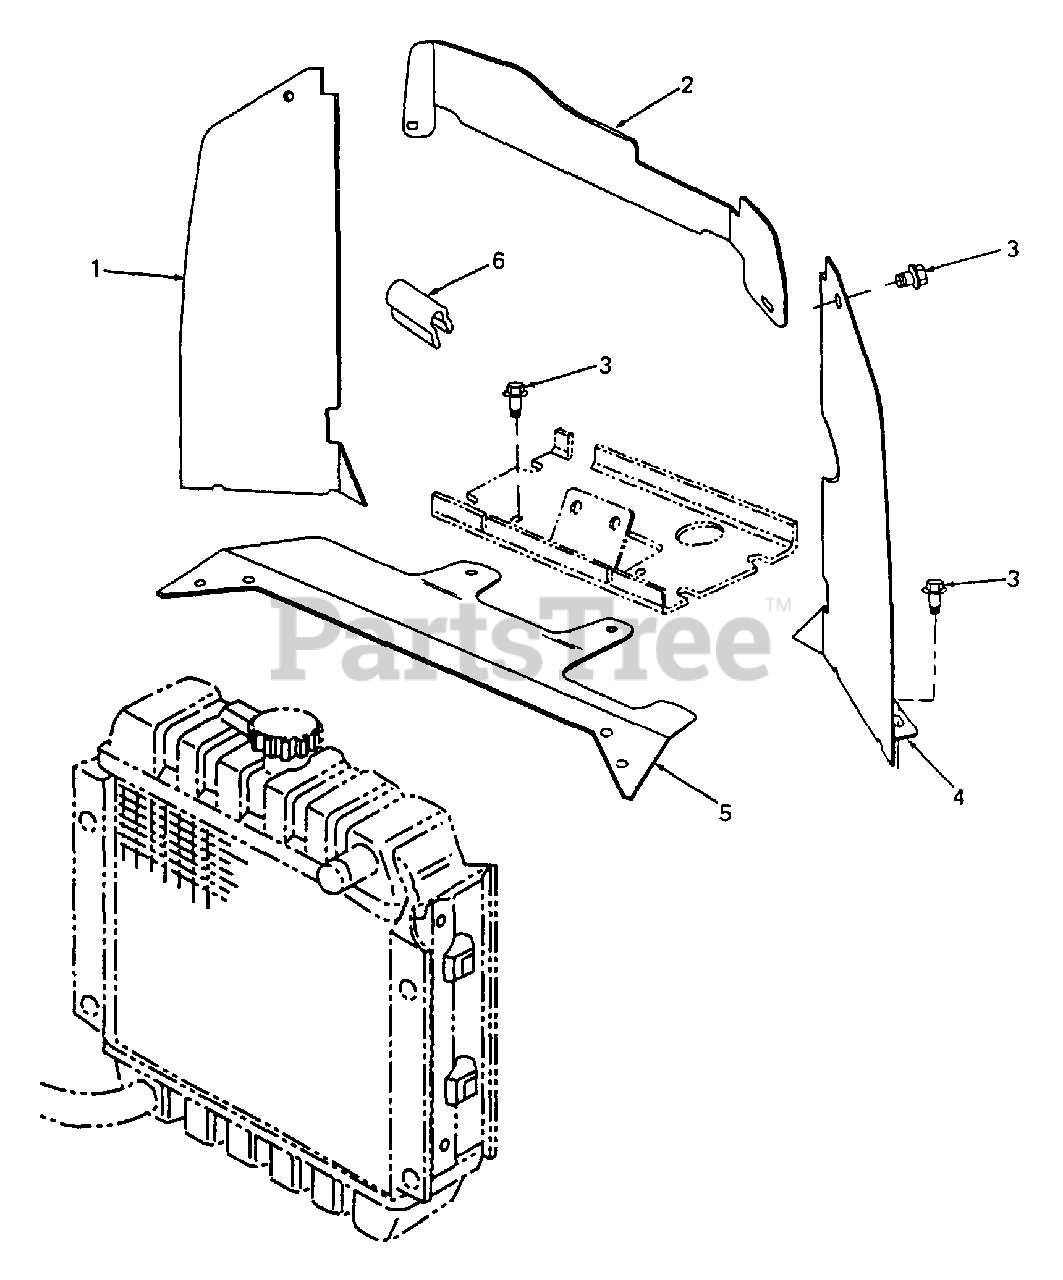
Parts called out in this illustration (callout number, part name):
1	Baffle, Radiator, Right
2	Baffle, Radiator, Top
3	Screw, Hex Wash, Tapp, 1/4-20 x .38 Lg
4	Baffle, Radiator, Left
5	Baffle, Radiator, Lower
6	Seal, Heat Baffle
